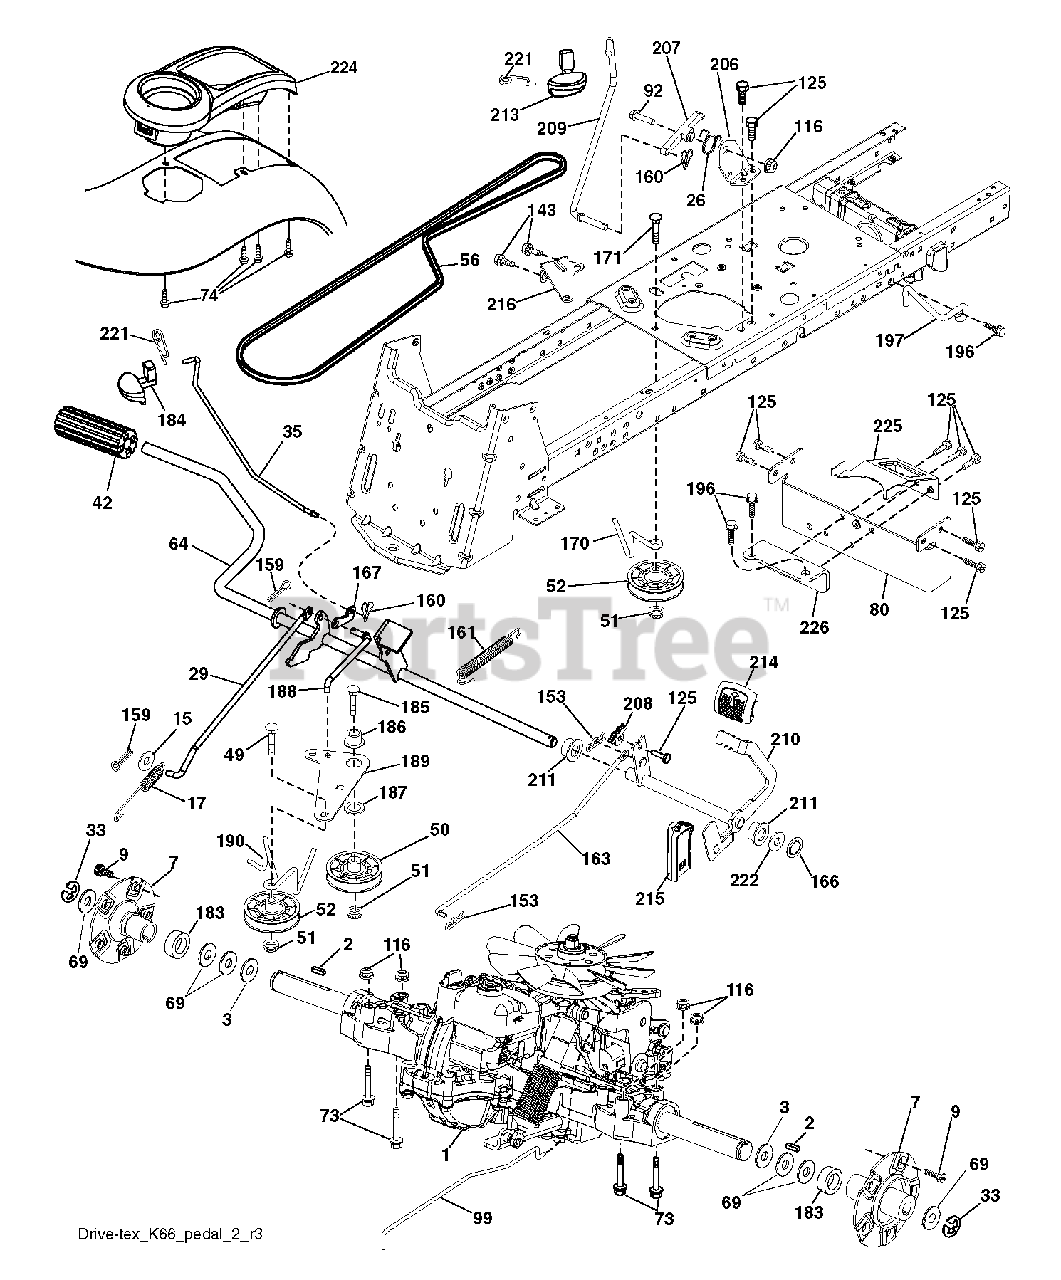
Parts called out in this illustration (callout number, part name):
3	WASHER T
7	\\B ASM. WHEEL
9	HUB BOLT
15	WASHER
17	SPRING.BRAKE.K46
26	SPRING.RETURN.CRUISE
29	ROD.BRAKE.K66
33	E RING HYT
35	ROD.BRKAE.PARKING.STEALTH
42	PEDAL COVER T
50	IDLER.FLAT.910.OFFSET
52	IDLER.V-GROOVE.910.OFFSET
64	SHAFT.ASM.PEDAL.BRK.CN
73	BOLT HEX 5/16-18 GR 5
74	SCREW,HEX
80	STRAP.TORQUE.K66
99	ROD.SPRING.BYPASS.K66.GT.Z
116	NUT LOCK HEX FLANGE 5/16-18
125	SCREW
143	SCREW LT
159	COTTER PIN
160	RETAINER CLIP
161	SPRING, RETURN LT
163	ROD.PEDAL.CONTROL
166	NUT.PUSH.625
167	LATCH BRAKE PARKING
170	KEEPER.V-IDLER.CENTER.
183	SPACER.AXLE.HG.TEX
186	SPACER.RETAINER
188	LINK.CLUTCH.GROUND DRI
189	BELLCRANK.GRDDRIVE.NST
190	KEEPER.BELLCRANK.DRIVE
196	SCREW 3/8-16X1
197	BRKT.ANIT-ROTATION.CLU
206	BRKT.MOUNT.LATCH.CRUIS
207	LATCH.CONTROL.CRUISE
208	GEAR.SECTOR.CONTROL.CR
209	ROD.CONTROL.CRUISE.STE
210	ROCKER.ASM.PEDAL.CONTR
211	BEARING RER
213	KNOB.CONTROL.CRUISE
214	PAD PEDAL FORWARD
215	PEDAL.REVERSE.TEX.GT.4
216	BRKT.PULLEY.IDLER.WTEX
221	RETAINER.SPRING.CLIP.H
222	WASHER 21/32 X 1-1/4 X 10 GA.
225	KEEPER.BELT.TRANSAXLE.K66
226	BRACKET.MOUNT.TORQUE.K66.TG
